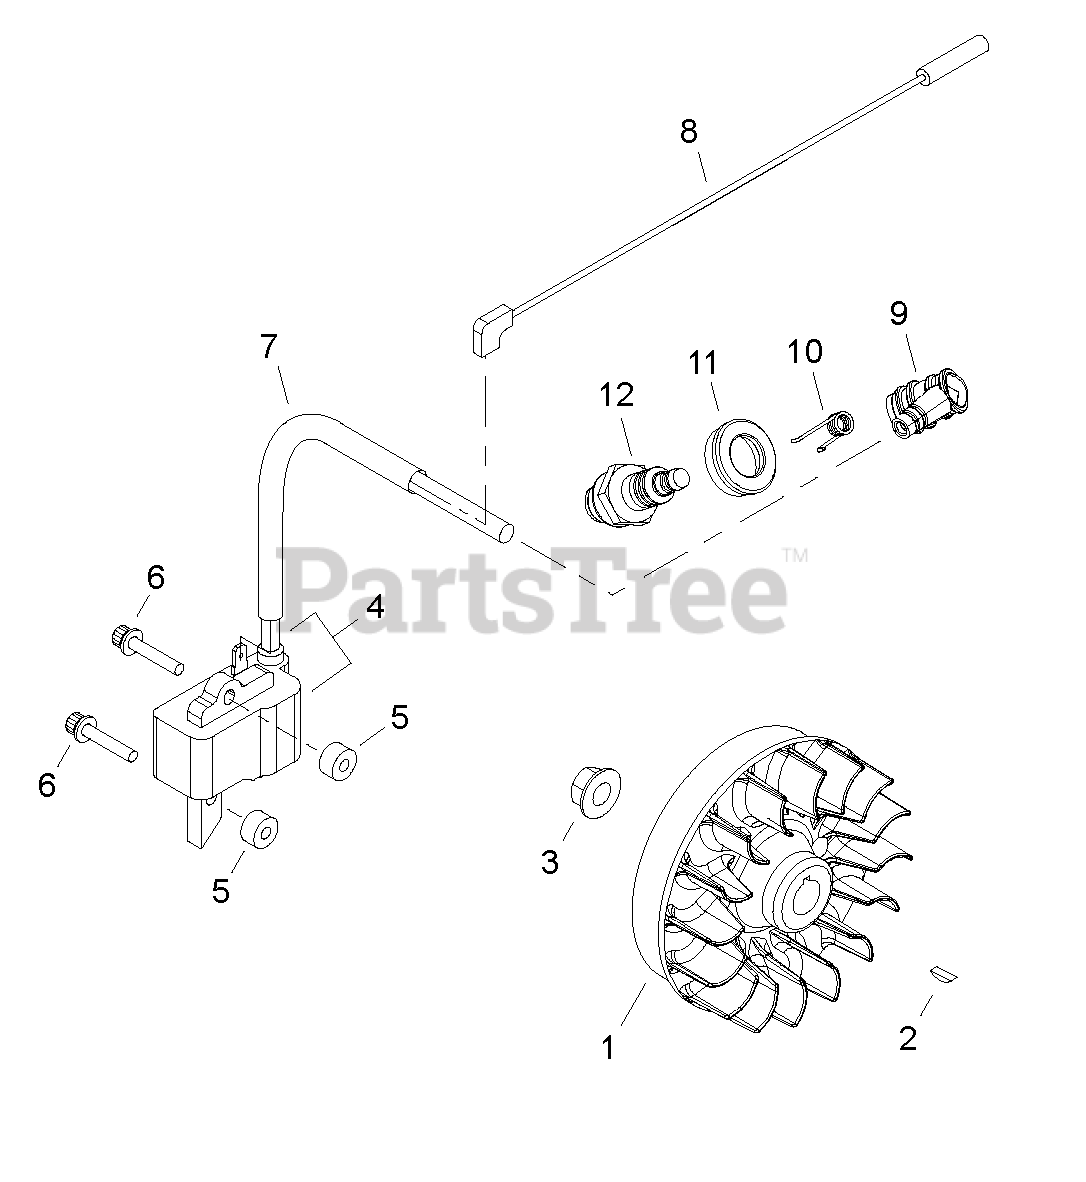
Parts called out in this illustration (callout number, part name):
1	FLYWHEEL
2	KEY - 3X10
3	NUT - 8
4	COIL, IGNITION
5	INSULATOR
6	SCREW - 4X20
7	TUBE
8	LEAD - IGNITION
9	CAP, SPARK PLUG
10	SEAL, DUST
11	TERMINAL, SPARK PLUG CAP
12	SPARK PLUG -- BPMR-6A
